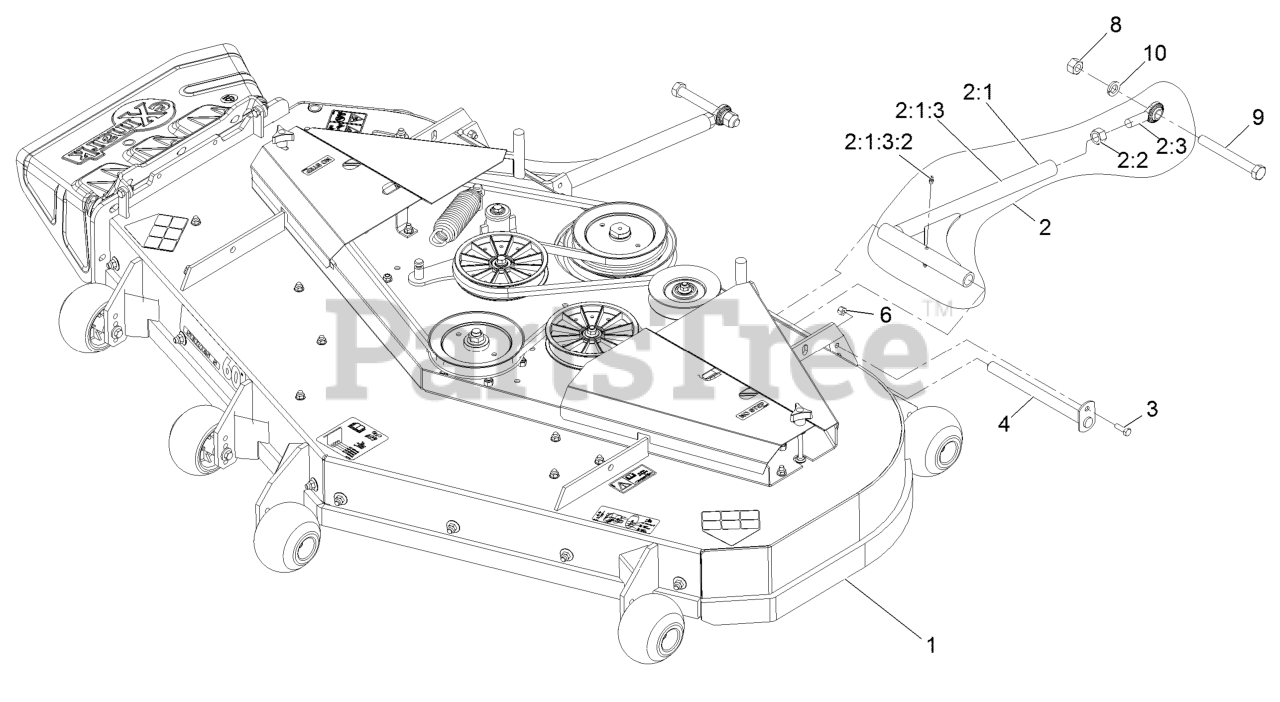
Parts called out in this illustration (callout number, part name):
1	ASM-Deck Complete 605
2	ASM,DECK STRUT XS 60
2:1	STRUT-DECK
2:1:3	Tube And Zerk ASM
2:2	NUT-HEX
2:3	BALLJOINT-SPHERICAL
3	SCREW-HH
4	PIN-STRUT
6	NUT-LOCK, NI
8	NUT-HEX
9	SCREW-HH
10	WASHER-LOCK
